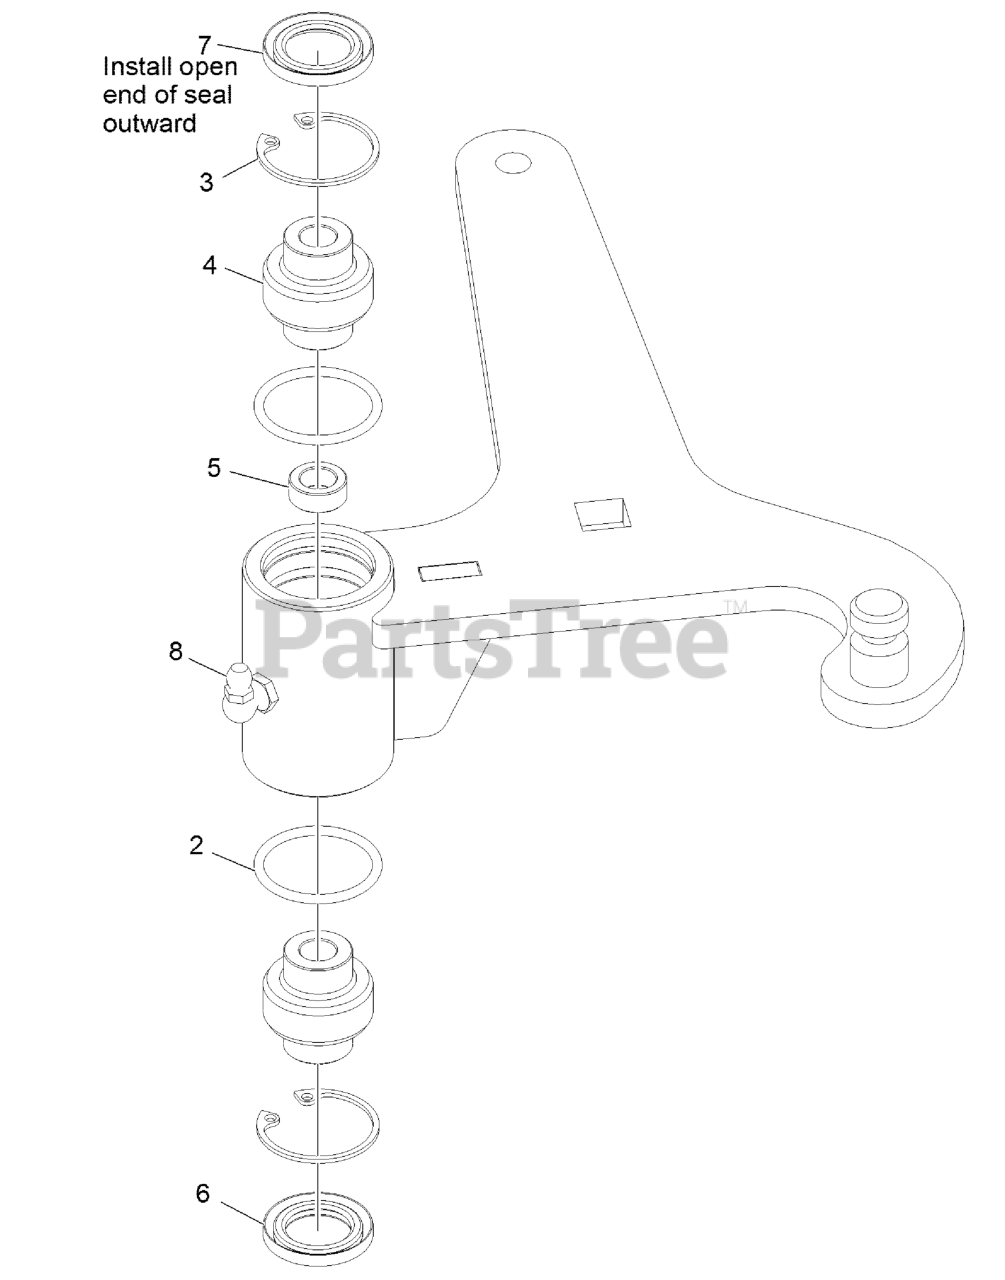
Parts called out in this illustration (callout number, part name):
3	RING-SNAP
4	BEARING-SPHERICAL
6	SEAL-LIP, DOUBLE
7	SEAL-LIP, SINGLE
8	FITTING-GREASE, 90 DEG
